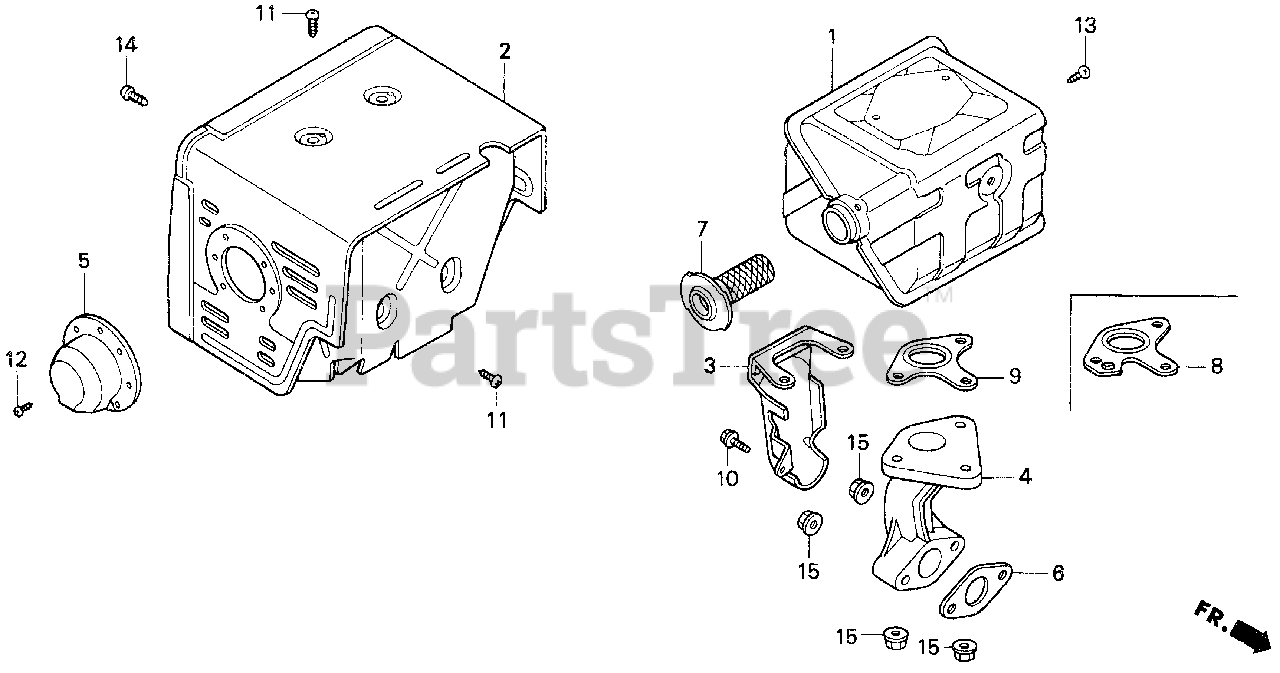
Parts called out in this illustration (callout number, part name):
1	MUFFLER (100DB) (SILENT)
1	MUFFLER (100DB)
2	PROTECTOR, MUFFLER
3	PROTECTOR, EX. PIPE
4	PIPE, EX.
5	CAP, MUFFLER
6	GASKET, EX. PIPE
6	GASKET, EX. PIPE (WACKER)
7	ARRESTER, SPARK
8	GASKET, MUFFLER (ARRESTER)
10	BOLT, FLANGE (6X12) (CT200)
11	SCREW, TAPPING (5X8)
12	SCREW, TAPPING (4X6)
13	SCREW, TAPPING (4X6)
14	SCREW, TAPPING (6X10)
15	NUT, FLANGE (8MM)
